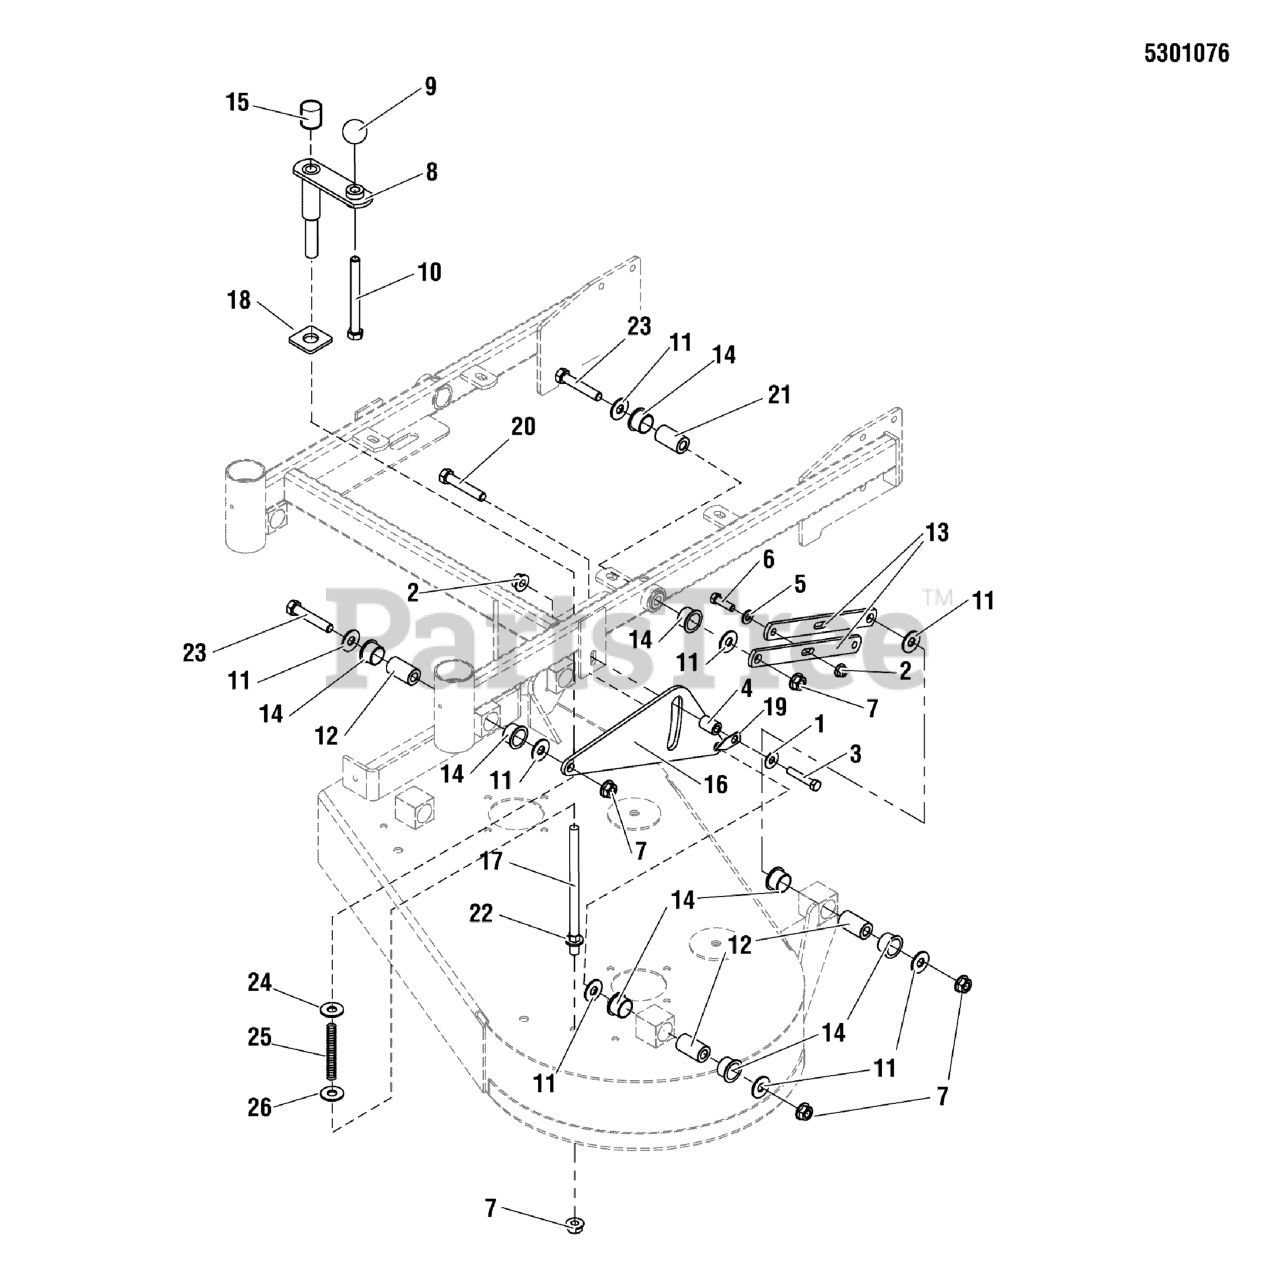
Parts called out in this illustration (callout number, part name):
1	WASHER, 3/8" USS
2	NUT, 3/8-16 HEX NYLOCK FLANGE
3	BOLT, 3/8-16 X 2, GD5, CZ
4	SPACER, .39 X .75 X 1.06
5	WASHER, 3/8 GD.9 FLAT
6	BOLT, 3/8-16 X 1-1/4" GD5 CZ
7	NUT, Hex Flange, Nylock, 1/2-13
8	CRANK, Deck
9	KNOB, PLASTIC, 1/2-13
10	BOLT, 1/2-13 X 5 GD5 YZ
11	WASHER, 1/2 USS
12	SPACER, .52 X 1.00 X 1.825
13	BAR, DECK LIFT - ADJ - RED
14	BUSHING, 1.00X1.13X.75, PLA
15	CAP, VINYL, .937 ID X 1.00
16	PLATE, DECK HEIGHT INDICATOR - SNP RED
17	ROD, DECK LIFT, STUD
18	WASHER, SQ, .715ID X 1.63SQ X 14TH, CZ
19	POINTER, DECK HEIGHT
20	BOLT, 1/2-13 X 3-1/2, HEX HD, GD5, CZ (SV)
21	SPACER, .50 X 1.00 X 2.25
22	HEX NUT, 1/2-13, SERRATED FLANGE, YZ
23	BOLT, 1/2-13 X 3" GD5 CZ
24	WASHER, 5/8 USS
25	SPRING, COMP, .695 X .885 X 7.5, BLACK
26	WASHER, 1/2 SAE
